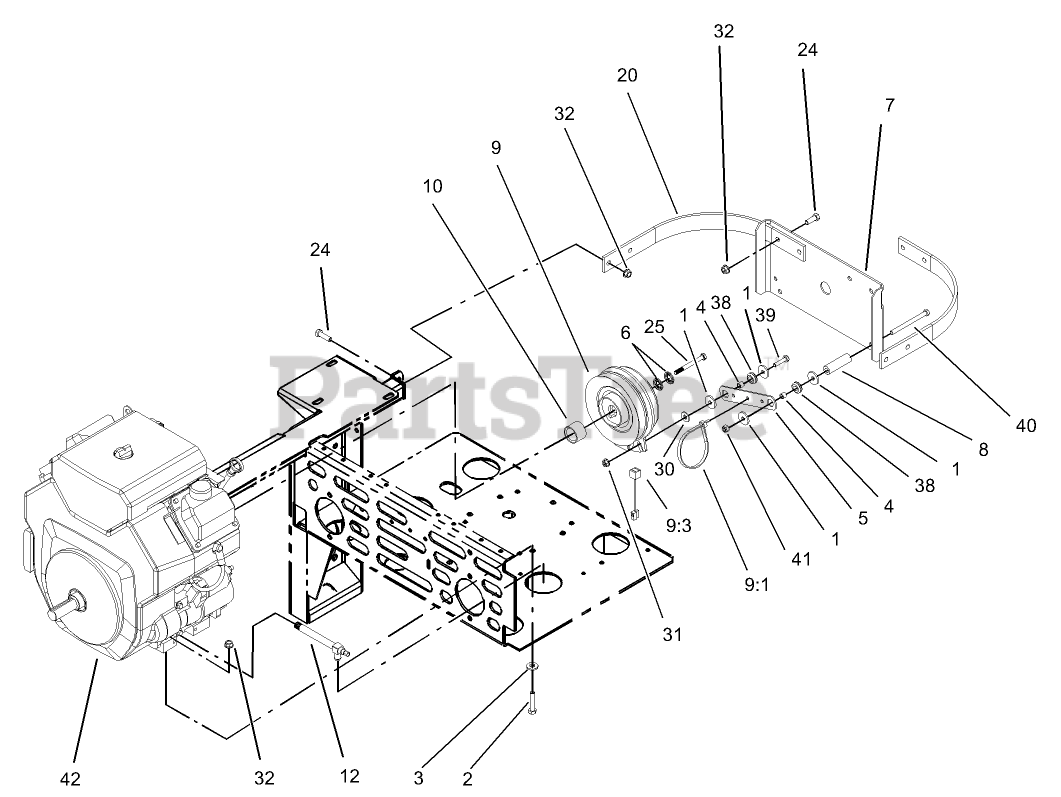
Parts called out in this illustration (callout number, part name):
1	WASHER
2	SCREW-HH
3	WASHER-BELLEVILLE
4	SPACER
5	STRAP-CLUTCH, BRAKE
6	WASHER-SPRING
7	GUARD-CLUTCH
8	SPACER-ANCHOR, CLUTCH
9	CLUTCH ASM
9:1	TIE-PLASTIC
9:3	HARNESS-JUMPER, CLUTCH
10	SPACER-CLUTCH
12	VALVE-OIL DRAIN, LONG
20	BRACKET-GUARD, TOP
24	SCREW-HH
25	SCREW-HH
30	WASHER-FLAT
31	NUT-HF
32	NUT-HHF, WHIZ
38	GROMMET
39	SCREW-HH
40	SCREW-HH
41	NUT-LOCK, NI
